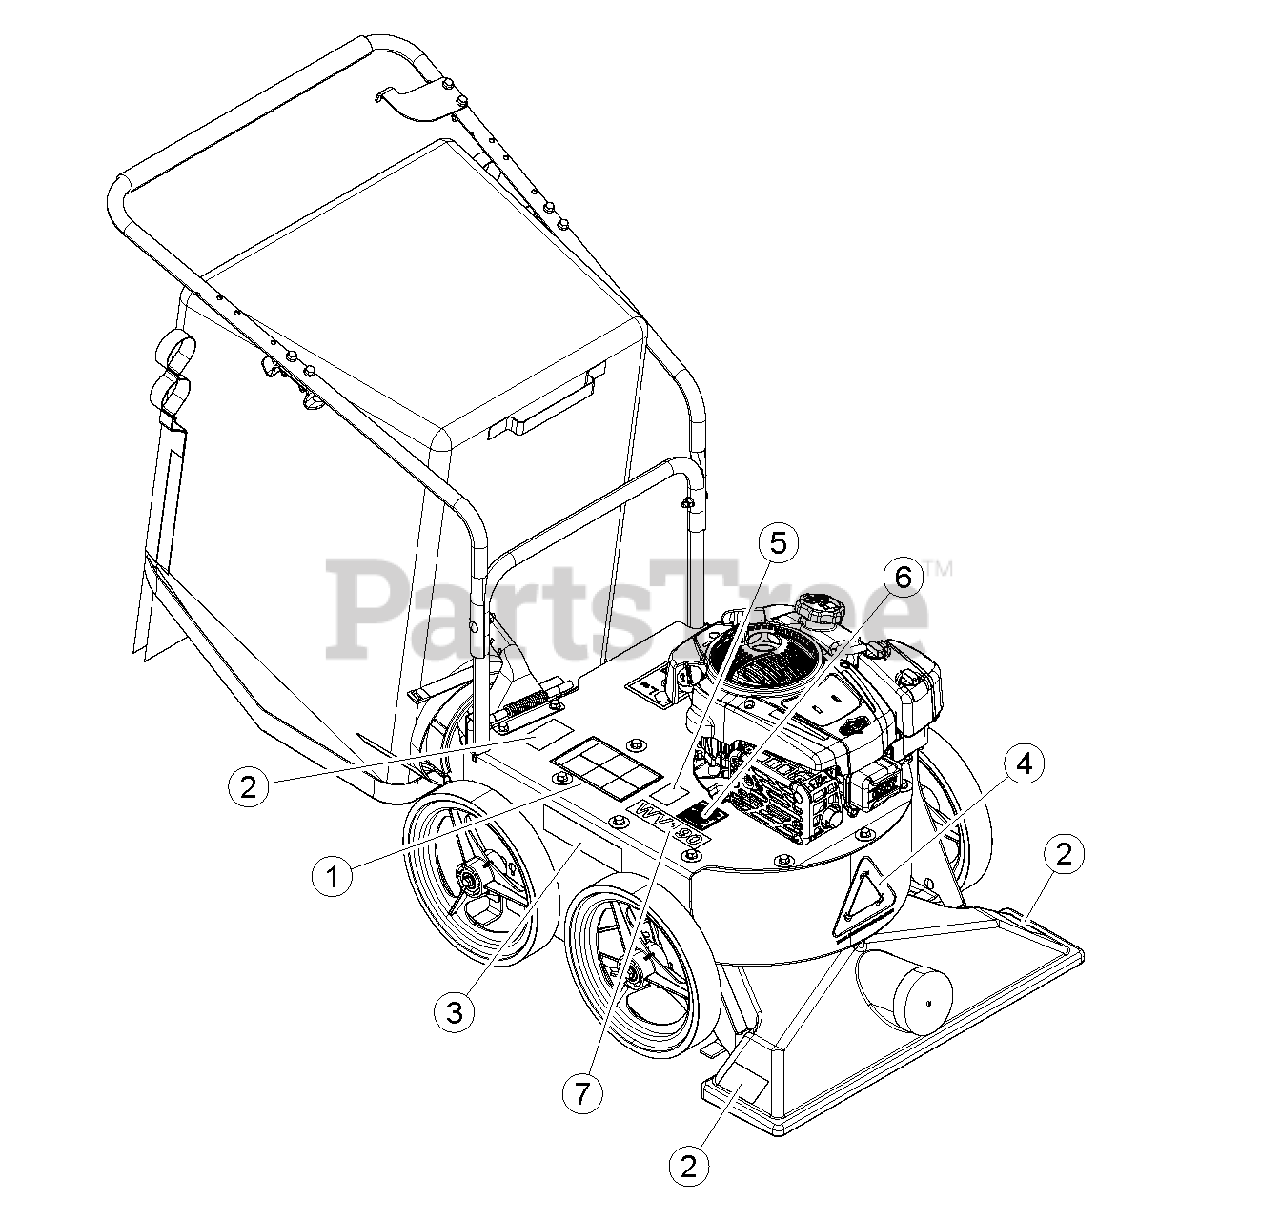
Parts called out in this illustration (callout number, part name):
1	DECAL, OPERATING INSTRUCTIONS ISO
2	DECAL, DANGER
3	DECAL, ECHO BEARCAT 6.82 X 1.90
4	LOGO, COLLECT IT (WHITE)
5	DECAL, ECHO BEARCAT QR CODE
6	DECAL, SPARK ARRESTOR
7	DECAL, MODEL WV160
